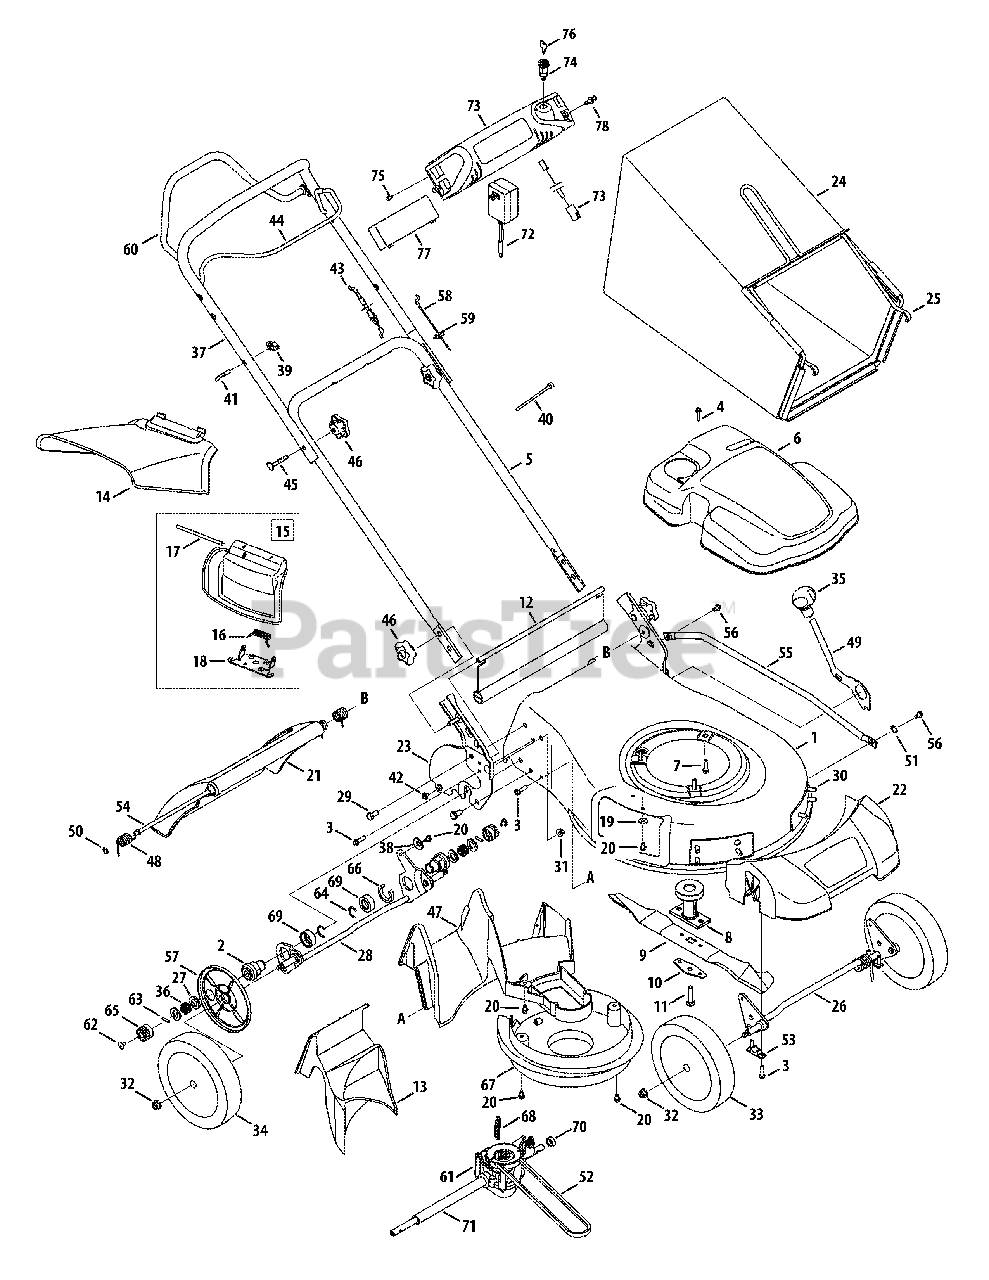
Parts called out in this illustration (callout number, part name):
2	Transmission Support Bearing
3	Screw, 1/4-15 x 1.000
4	Screw, HL, #12-16 x 1.00
5	Lower Handle
6	Engine Shroud
7	Screw, 3/8-16 x 1.00
8	Blade Adapter
9	Mulching Blade
10	Blade Bell Support
11	Screw, 3/8-24 x 1.50
12	Trailing Shield
13	Rear Mulch Plug
14	Side Discharge Chute
15	Mulch Plug (Incl. 16-18)
16	Torsion Spring
17	Hinge Pin
18	Chute Deflector Adapter
19	Belleville Washer
20	Screw
21	Rear Door
22	Front Cover
23	Handle Bracket - RH
23	Handle Bracket - LH
24	Grass Bag
25	Grass Bag Frame
26	Front Bracket Assembly
27	Washer, Flat, .508 x 1.00 x .020
28	Self Propelled Bracket Ass’y
29	Hhcs, 5/16-18 x .625
30	Screw, 5/16-14 x .750
31	Nut, Flange Lock, 5/16-18
32	Nut, Flange Lock, 3/8-16
33	Front Wheel
34	Rear Wheel
36	Wave Spring
37	Upper Handle
38	Washer, Bell, .340 x .872 x .060
40	Cable Tie
40	Guide, Cable
41	Rope Guide
42	Screw, #10-16 x .500
43	Control Cable
44	Blade Control
45	Bolt Carriage, 5/16-18 x 2.0
46	Star Knob
47	Rear Baffle
48	Door Torsion Spring - RH
48	Door Torsion Spring - LH
49	Spring Lever
50	Nut, Push
51	Wshr, Wave, .385 ID x .598 OD
52	V-Belt
53	Bushing, Lock, .505 Dia. X .62
54	Rear Door Pivot Rod
55	Cross Bracket
56	Scr., Shldr., 1/4-20 x .50
57	Wheel Dust Cover
58	Drive Cable
59	Grommet
60	Drive Control
61	Transmission
62	Screw, 1/4-20 x .390
63	Dowel Pin
64	Retainer Ring
65	Spur Gear - RH
65	Spur Gear - LH
66	Spacer, Clip
67	Engine Baffle
68	Exten. Spring, .429OD x 2.515
69	Bearing Support Spacer
70	Sleeve Spacer, .550ID x .340 Lg.
71	Sleeve Spacer, .550ID x 7.97 Lg.
72	Battery Charger
73	Electric Start Harness Assembly
74	Key Switch
75	Screw, #10-16 x .750
77	Battery
78	Rivet
